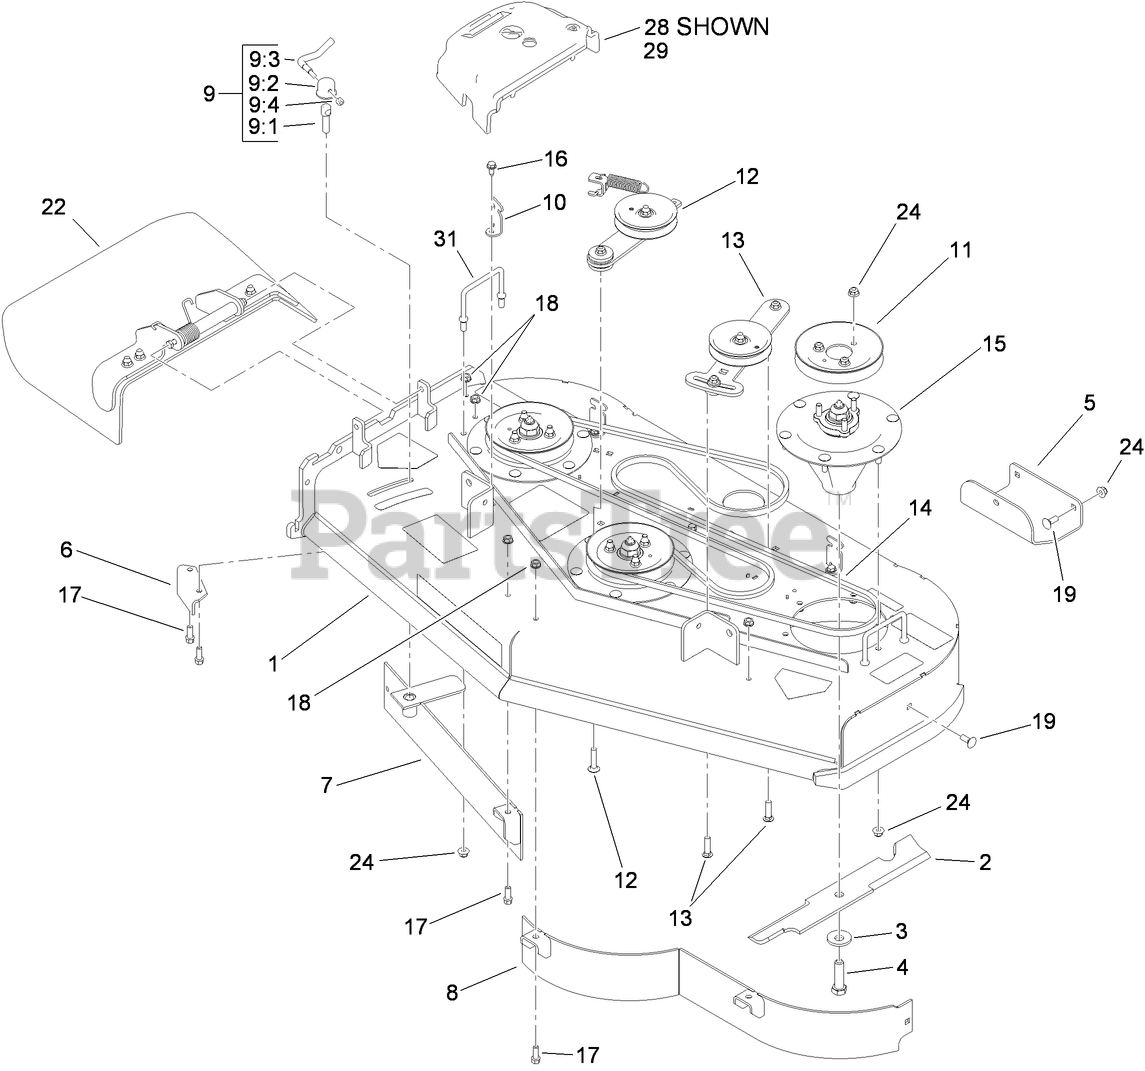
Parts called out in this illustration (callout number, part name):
1	DECK ASM
2	BLADE-16.5 INCH (HIGH FLOW)
3	Washer-Blade Bolt, Heavy
4	SCREW-BLADE
6	BAFFLE-DISCHARGE
7	BAFFLE ASM
8	48 INCH BAFFLE ASM
9	LEVER ASM
9:1	Screw-Lock
9:2	CAP-LOCK
9:3	Lever-Lock
9:4	NUT-LOCK, NI
10	BRACKET-COVER
11	PULLEY
12	SPRING IDLER ASM
13	IDLER ADJUST ASM
14	BELT-V
15	SPINDLE ASM
16	SCREW-HWHTF
17	SCREW-HWH
18	NUT-HHF, WHIZ
19	BOLT-CARR
22	DEFLECTOR ASM
24	NUT-HF, NI
28	COVER-BELT, RH
29	COVER-BELT, LH
31	WIREFORM-COVER
